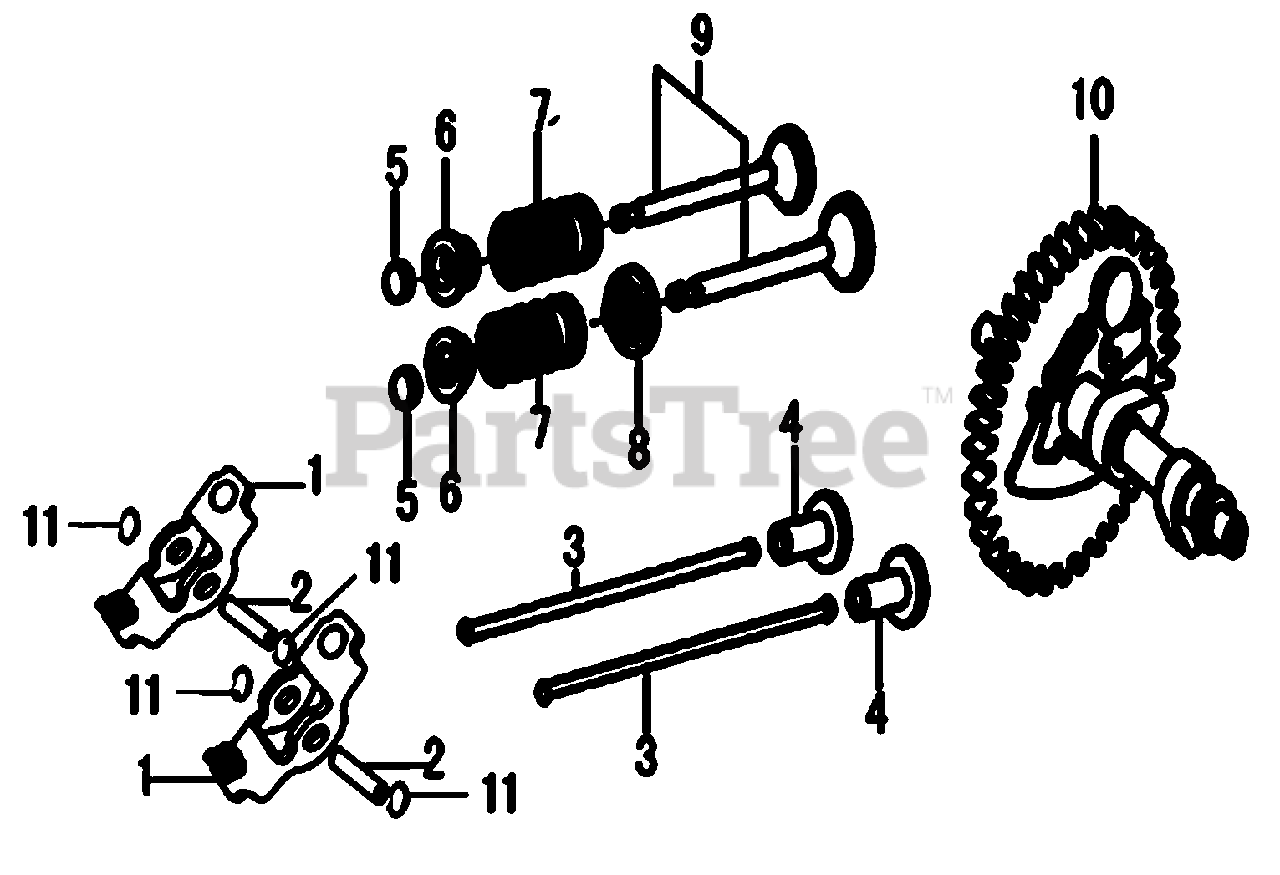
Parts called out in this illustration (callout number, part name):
1	ROCKER ARM
2	VALVE ROCKER SHAFT
3	ROD, PUSH
4	LIFTER VALVE
5	ROTATOR, VALVE
6	RETAINER, VALVE SPRING
7	SPRING, VALVE
8	SEAL, GUIDE
9	VALVES, INTAKE & EXHAUST SET OF 2
10	CAMSHAFT ASSY.
11	SPLIT WASHER
